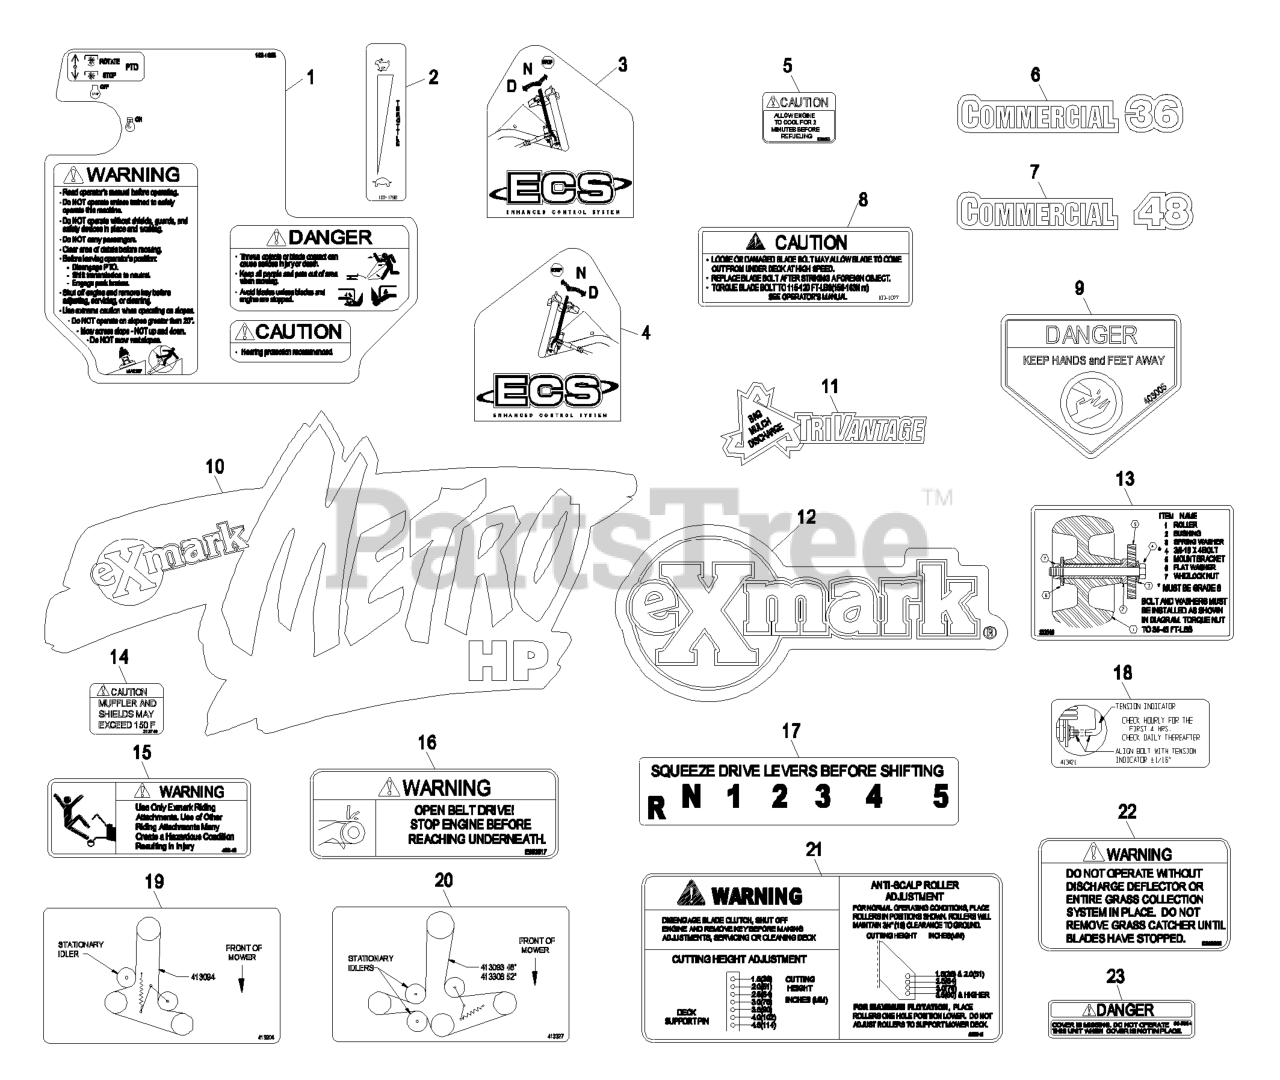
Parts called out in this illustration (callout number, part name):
1	DECAL,METRO ECS CONSOLE
2	DECAL,THROTTLE ONLY
3	DECAL,LH ECS INSTRUCTION
4	DECAL,RH ECS INSTRUCTION
6	DECAL,COMMERCIAL 36
7	DECAL,COMMERCIAL 48
8	DECAL,BOLT TORQUE
9	DECAL-DANGER
13	DECAL,ROLLER MOUNTING
15	DECAL,SULKY WARNING
16	DECAL,BELT DRIVE
17	DECAL,SHIFTER
18	DECAL,INDICATOR
19	DECAL,BELT ROUTING
20	DECAL,BELT ROUTING
21	DECAL,ANTI SCALP
22	DECAL-WARNING, DISCHARGE
23	DECAL-COVER, MISSING
